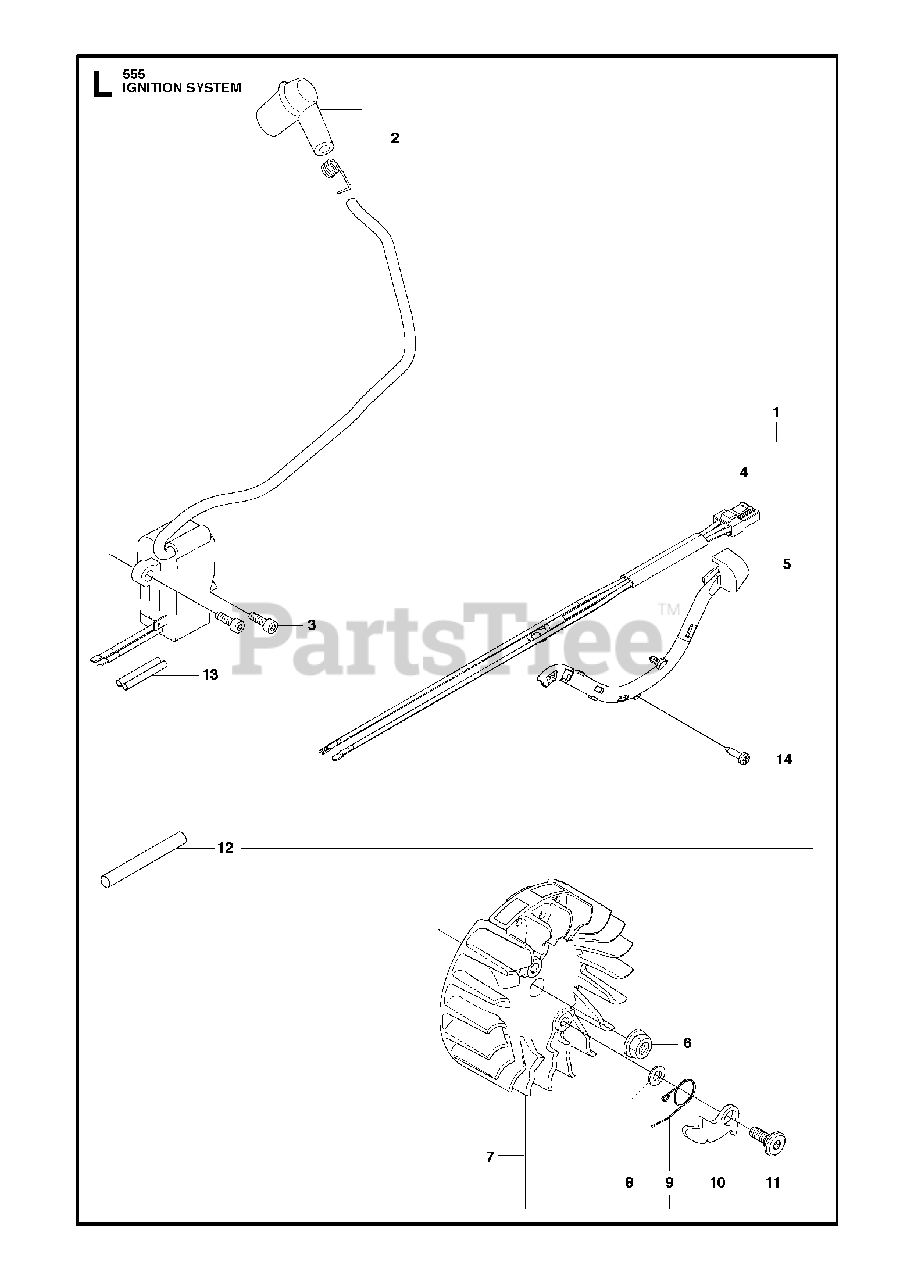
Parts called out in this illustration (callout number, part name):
1	IGNITION MODULE ASSY
2	SPARK PLUG CAP ASSY
4	WIRING ASSY
5	CABLE HOLDER
6	NUT W/ WASHER
7	FLYWHEEL ASSY
8	WASHER
9	SPRING
10	PAWL
11	SCREW M5X14
12	CABLE COVER
13	SHRINK HOSE
